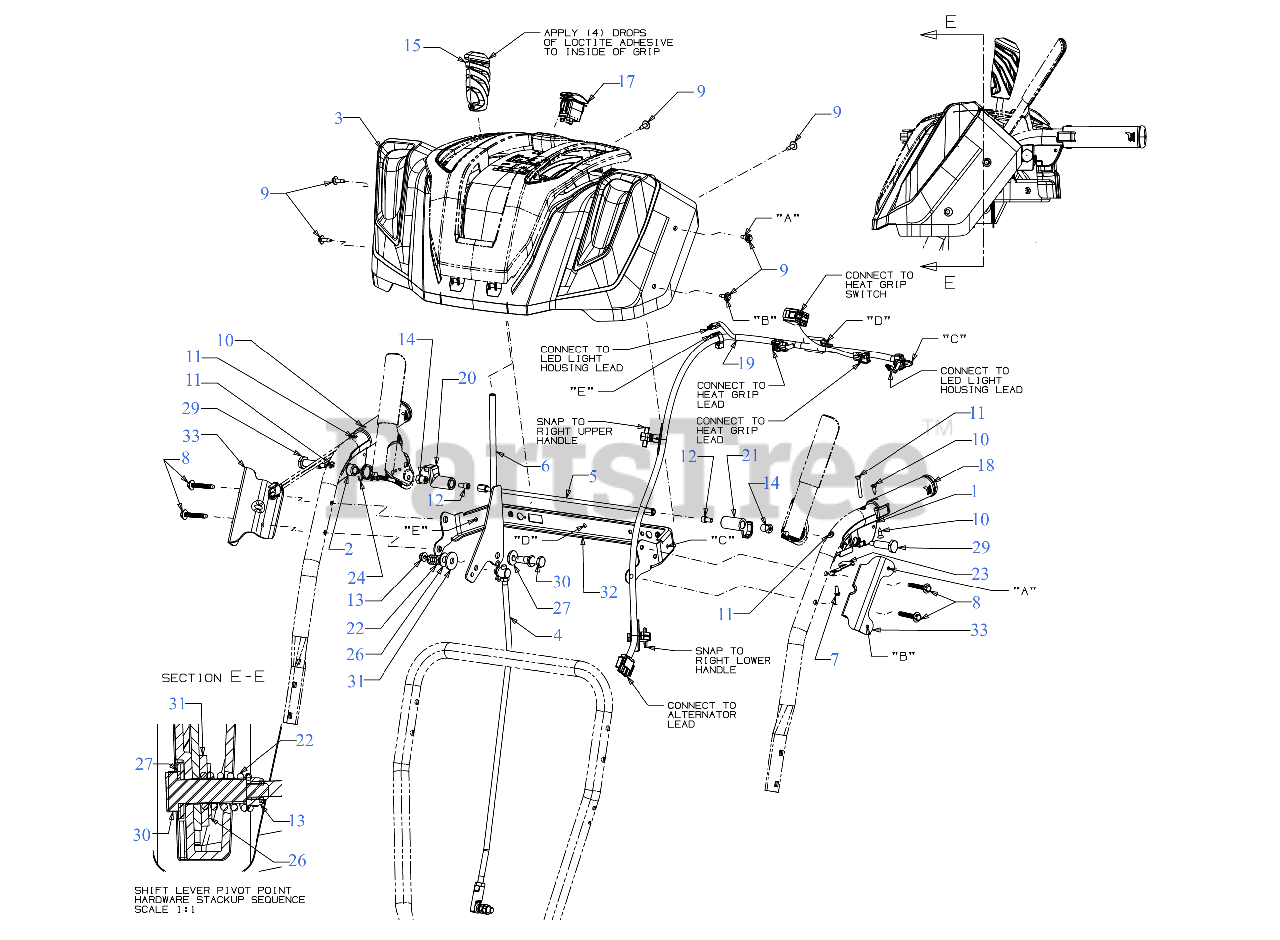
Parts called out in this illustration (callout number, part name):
1	CLUTCH LOCK HANDLE ASSEMBLY (LH)
2	CLUTCH LOCK HANDLE ASSEMBLY (RH)
3	ASSEMBLY
3	HANDLE PANEL ASSEMBLY
3	SCREW M6-1 x .625
3	LENS-LED SNOW
3	LED HEADLIGHT HARNESS ASSEMBLY
4	ASSEMBLY
6	SHIFT LEVER (POWDER BLACK)
7	SCREW #8-16 x .50
8	SCREW 1/4-20 x 1.625
9	SCREW M6-1 x .625
10	SCREW #10-16 x .625
11	SCREW #10-24 x 1.375
12	SCREW 1/4-20 x .50
13	FLANGE LOCK NUT
14	HEX NUT W/PATCH
15	PTO HANDLE GRIP .355 ID
17	HEATED GRIP SWITCH
18	HARNESS-SNOW HEATED GRIP RED
19	HARNESS (TWO HEADLIGHT)
21	CLUTCH LOCK CAM
22	COMPRESSION SPRING
23	CLUTCH SPRING
24	TORSION SPRING
26	FLAT WASHER
29	SHOULDER SCREW .437 x 1.345 1/4-20
30	SHOULDER SCREW
31	FRICTION WASHER
32	HANDLE SUPPORT BRACKET (POWDER BLACK)
33	HANDLE PANEL BRACKET (POWDER BLACK)
